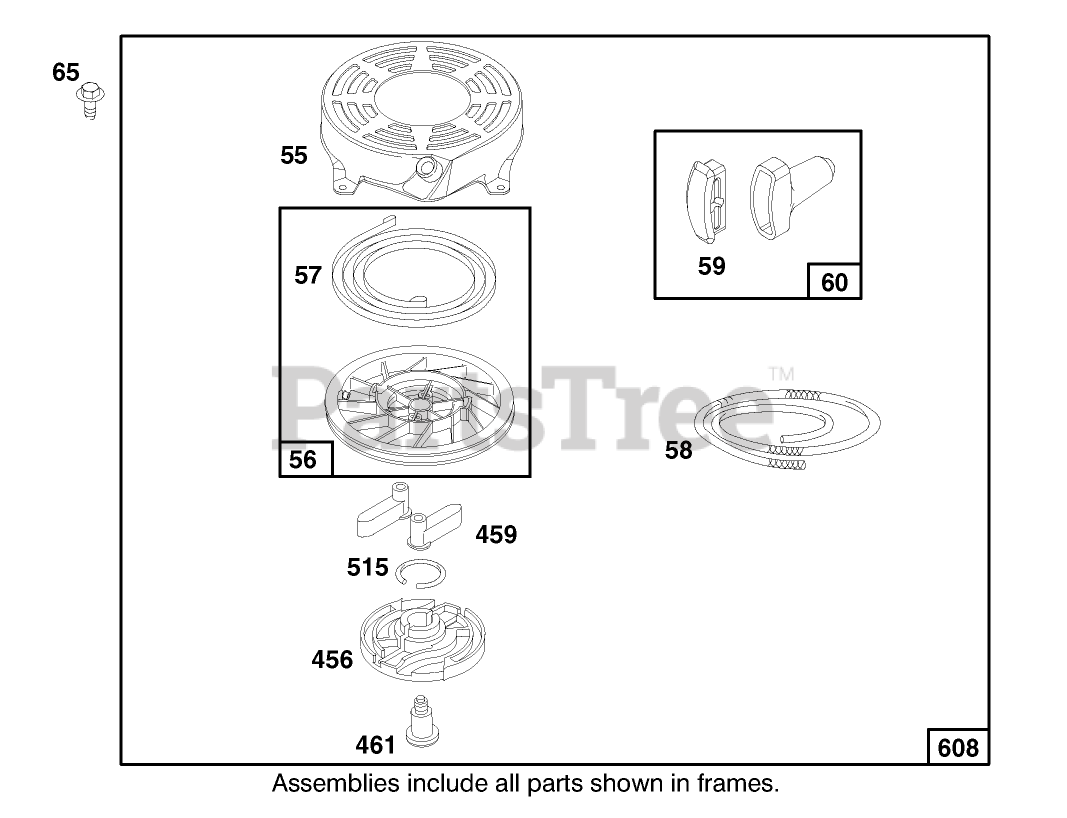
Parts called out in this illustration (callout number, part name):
56	PULLEY-STARTER, REWIND
59	INSERT-HANDLE, REWIND
456	RETAINER-STARTER, REWIND
459	PAWL-STARTER
515	SPRING-TORSION
